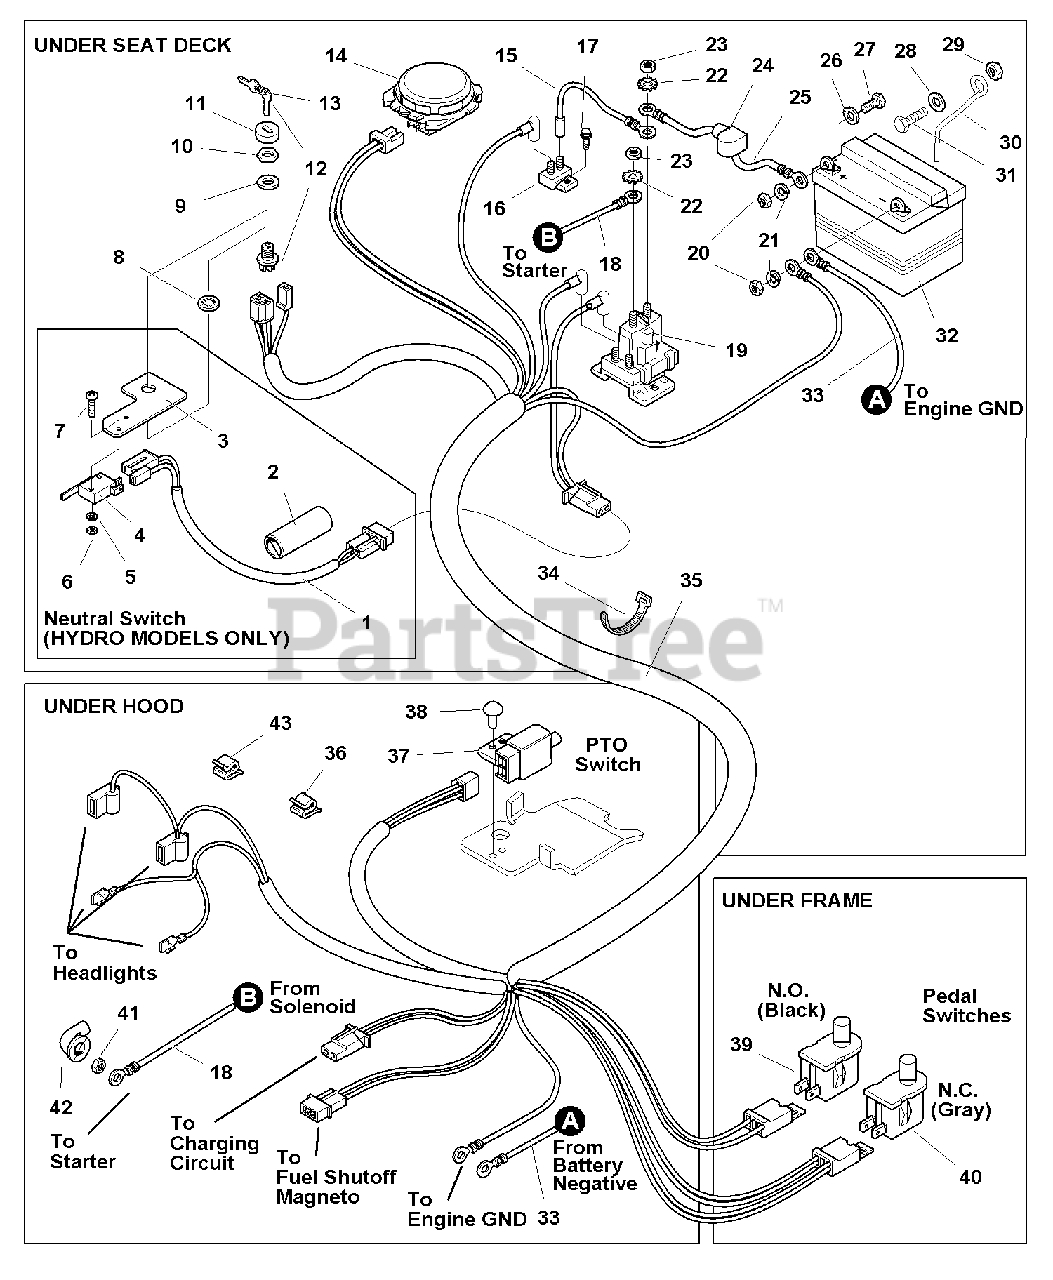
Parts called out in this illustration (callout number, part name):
1	WIRE ASSEMBLY
2	TUBE, Shrink
3	PLATE, Neutral Switch
4	SWITCH, Neutral Safety
5	LOCKWASHER, Spring, 1/8
6	NUT, Hex Machine, #5-40
7	CAPSCREW, Round Head, Phillips, #5 - 40 x 3/4
8	LOCKWASHER, Internal Tooth, 5/8
9	WASHER, 5/8
10	NUT, Hex, Flange, 5/8-32
11	COVER, Ignition
12	SWITCH, Ignition, 6-Pole (Includes Ref. Nos. 9, 10, 11, 12 &13)
13	IGNITION KEY (Set of 2)
14	SWITCH, Seat, Gray Switch, Gray Retainer
14	SWITCH, Seat, Gray Switch, Black Retainer
15	WIRE ASSEMBLY
16	CIRCUIT BREAKER
17	CAPSCREW, Taptite Hex Washer Head, 1/4-20 x 5/8
18	CABLE, # 6 x 42-1/2 long (Solenoid to Starter)
19	SOLENOID
20	NUT, Hex, 1/4-20
21	LOCKWASHER, 1/4
22	LOCKWASHER, External Tooth, 5/16
23	NUT, Hex, 5/16-24 NF
24	BOOT, Insulator
25	CABLE, # 6 x 10 Long, with 2 Ring Terminals
26	WASHER, Plain, 1/4
27	CAPSCREW, Hex Head, 1/4-20 x 3/4
28	WASHER, Plain, 5/16
29	NUT, Hex Nylon Lock, 5/16-18
30	ROD, Battery Hold Down
31	CAPSCREW, Hex Head, 5/16-18 x 3/4
33	CABLE, # 6 x 52-1/2 long (Battery to Ground)
34	TIE-SELF LOCKING
35	HARNESS, Wiring
36	CLIP, Wire
37	SWITCH, Neutral Start
39	SWITCH, Pedal, N.O., Black
40	SWITCH, Pedal, N.C., Gray
41	NUT, Hex Flange, Whiz Lock, 1/4-20
42	COVER, Terminal
43	CLIP, Tinnerman
